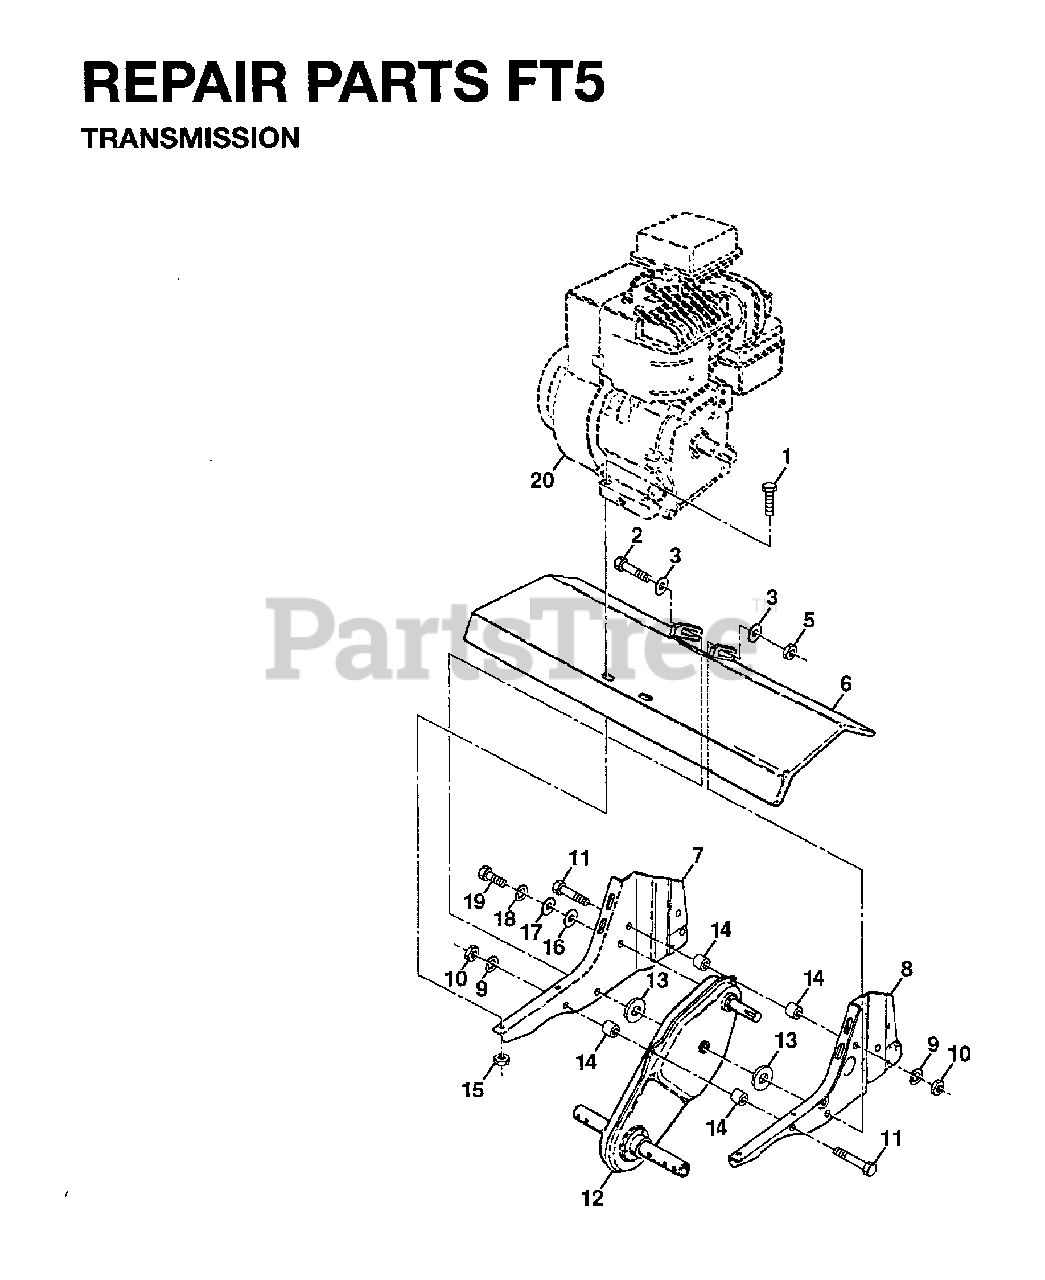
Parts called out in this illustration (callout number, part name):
1	TRANSMISSION ASSEMBLY
2	GEARCASE LH W/BRG
3	GASKET TI
4	NEEDLE BRNG LT
5	THRUST WASHER
6	GEAR.PINION.INPUT
7	SHAFT.INPUT."D".TILLER
8	BEARING TI
9	WASHER SEAL CRT
10	STEEL BALL KIT
11	SPRING-SHIFT CRT
12	O-RING TI
13	SHIFTING ARM
14	SHIFT FORK TI
15	KLIP RING
16	SHIFT SHAFT
19	KLIP RING
20	GEAR ASSY CRT
21	GEAR-REV IDLR CRT
22	NEEDLE BEARING TI
23	SHAFT CRT
24	LOCKWASHER
27	BEARING, SHAFT LH CRT
29	CHAIN CRT
30	GROUND SHAFT ASS'Y
31	BEARING, SHAFT RH CRT
32	SPACER TI
33	SPRCKT 8 GEAR CRT
34	SHAFT.SECONDARY.REDUCTION.CRT
35	SCRW WHIZ LOK CRT
36	SPROCKET ASSY W/ BRG
37	BEARING
38	SPROCKET ASSY W/ BRG
39	GEAR TI
41	SHAFT.REDUCTION.TILLER
42	BRNG RACE T
43	SPACER TI
44	CUP
45	RING SPIRAL CRT
47	OIL SEAL STD
48	GEARCASE RH W/BRG
49	TINE SHAFT
50	CHAIN.TILLER
51	BOLT
53	BEARING KIT
